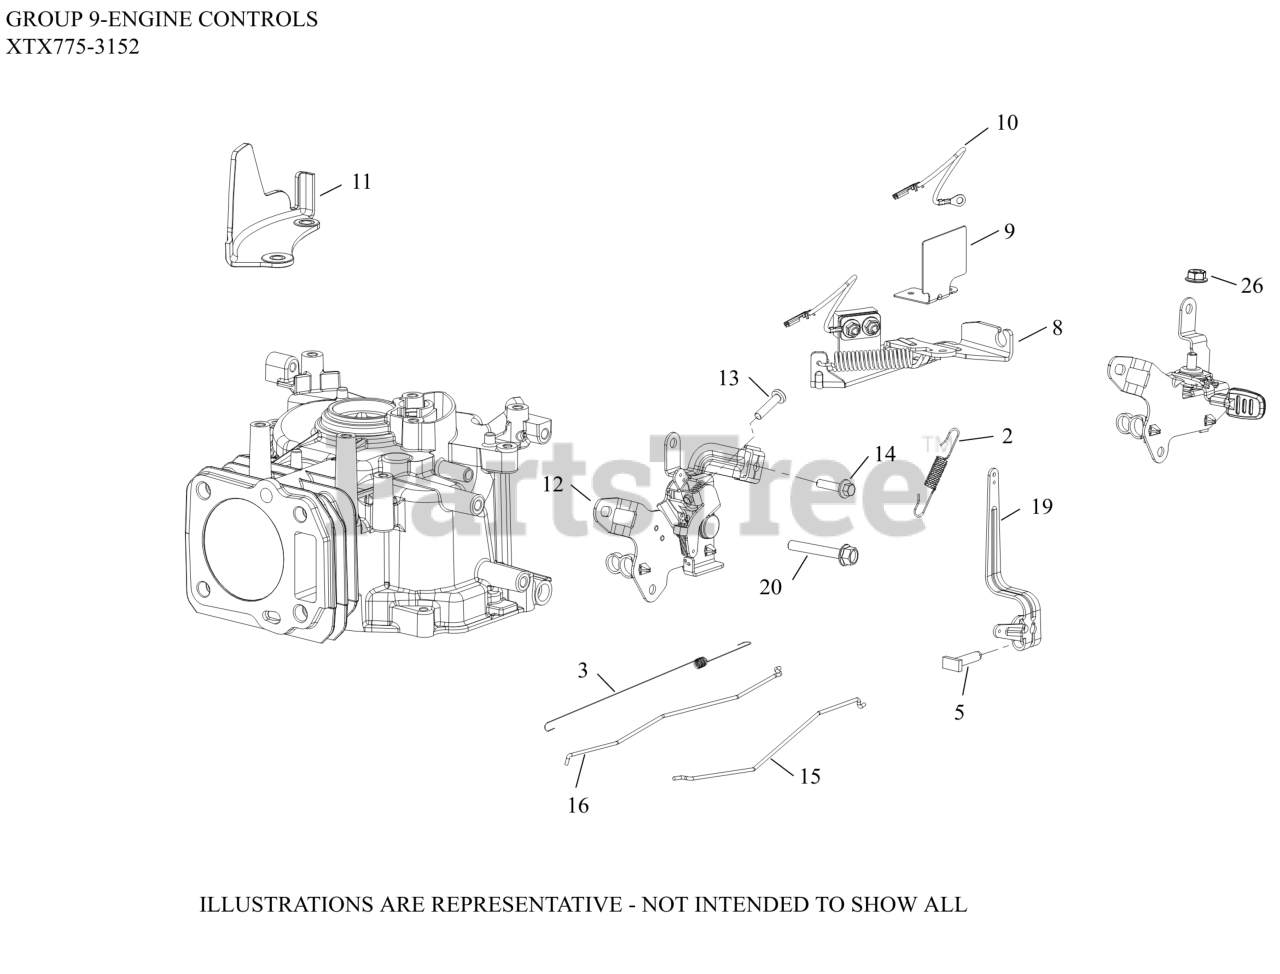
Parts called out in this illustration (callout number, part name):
2	SPRING, GOV (2800-3300 RPM)
3	SPRING, LINKAGE
5	SCREW, RECTANGLE HEAD (M6)
8	BRAKE ASSEMBLY
9	GUARD, BRAKE - USE 14 314 30-S
10	LEAD, KILL (BRAKE TO IGN. MODULE)
11	GUARD, FINGER
12	CONTROL ASSEMBLY (VAR. SPEED)
13	SCREW, #25 6-LOBE PAN HD (M5)
14	SCREW, (M5) HEX FLANGE
15	LINKAGE, CHOKE-(#DSC)
16	LINKAGE, GOVERNOR
19	LEVER, GOVERNOR
20	SCREW, HEX FLANGE (M6)
26	NUT, HEX FLANGE LOCK (M6)
